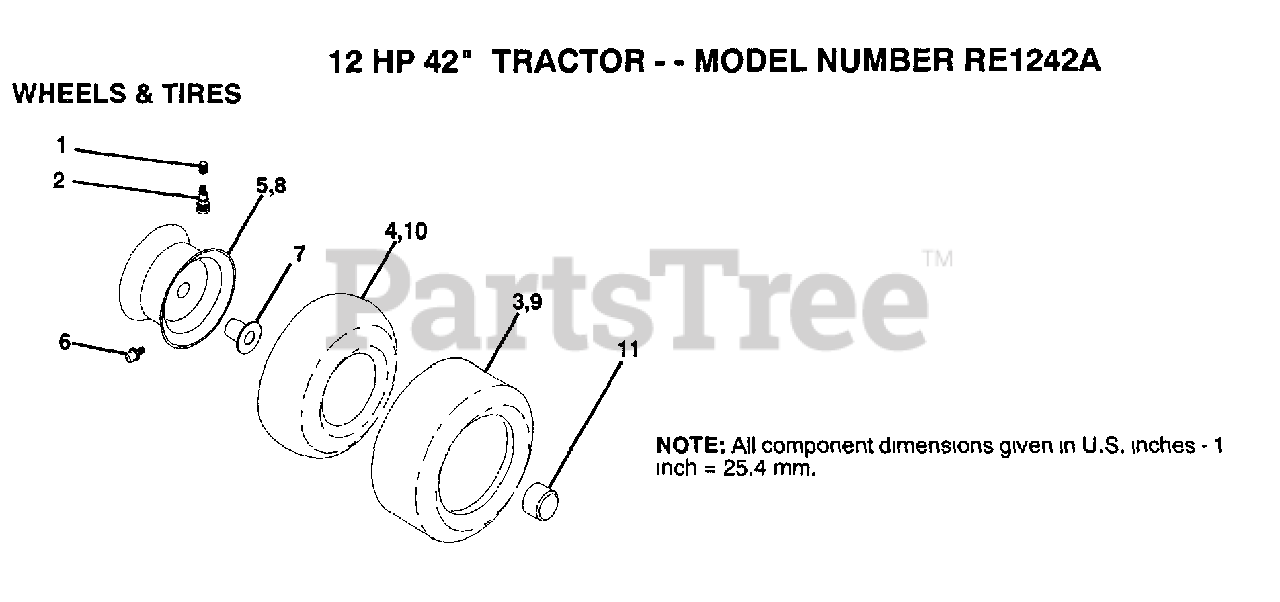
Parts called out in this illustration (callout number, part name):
1	VALVE CAP
2	VALVE STEM LT
4	TUBE.5.3/4.5/6
6	FITTING LT
7	"FLANGE, BEARING"
10	TUBE.18X9.5-8
11	HUB CAP
